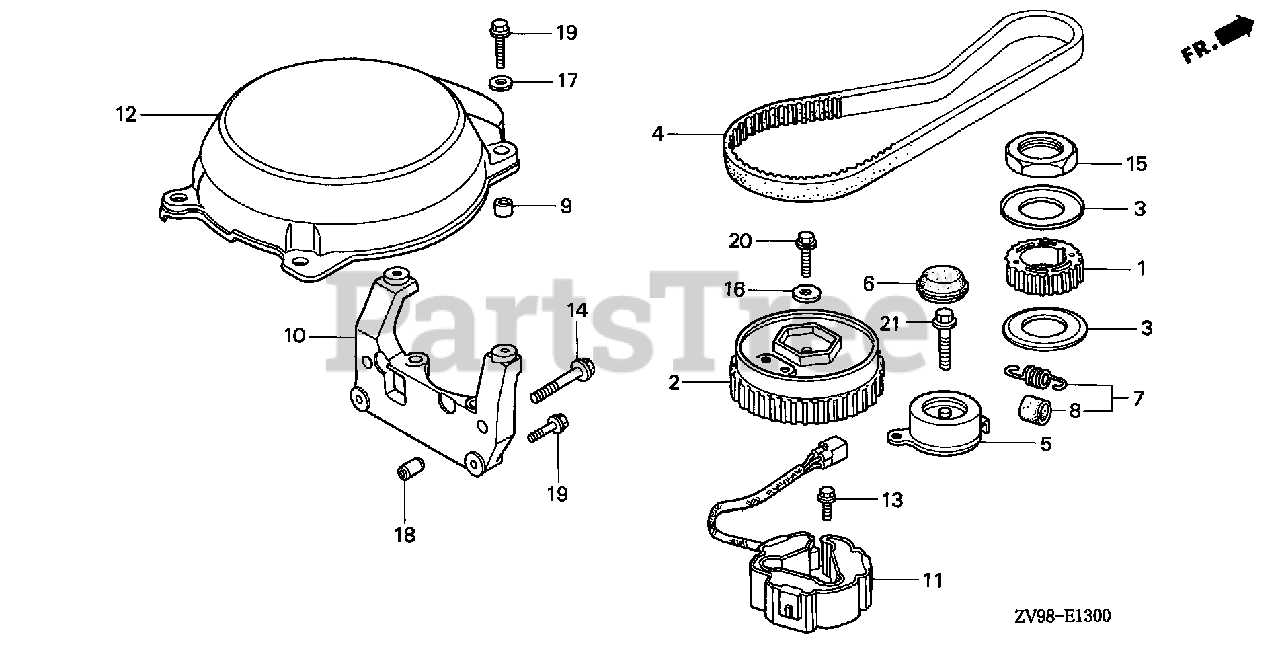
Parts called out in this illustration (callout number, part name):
1	PULLEY, TIMING
2	PULLEY, CAMSHAFT
3	PLATE, TIMING BELT GUIDE
4	BELT, TIMING
5	TENSIONER, TIMING BELT
6	CAP, TIMING BELT TENSIONER
7	SPRING, TIMING BELT ADJUSTING
8	BOOT, SPRING
9	COLLAR, DISTANCE (6.5X11X7.5)
10	BRACKET, RECOIL
11	COIL ASSY., PULSER
12	COVER, FLYWHEEL
13	BOLT, FLANGE (6X12)
14	BOLT, FLANGE (8X45)
15	NUT, LOCK (34MM)
16	WASHER, PLAIN (8MM)
17	WASHER (6.5X18)
18	PIN, DOWEL (10X16)
19	BOLT, FLANGE (6X22)
20	BOLT, FLANGE (8X25)
21	BOLT, FLANGE (10X38)
